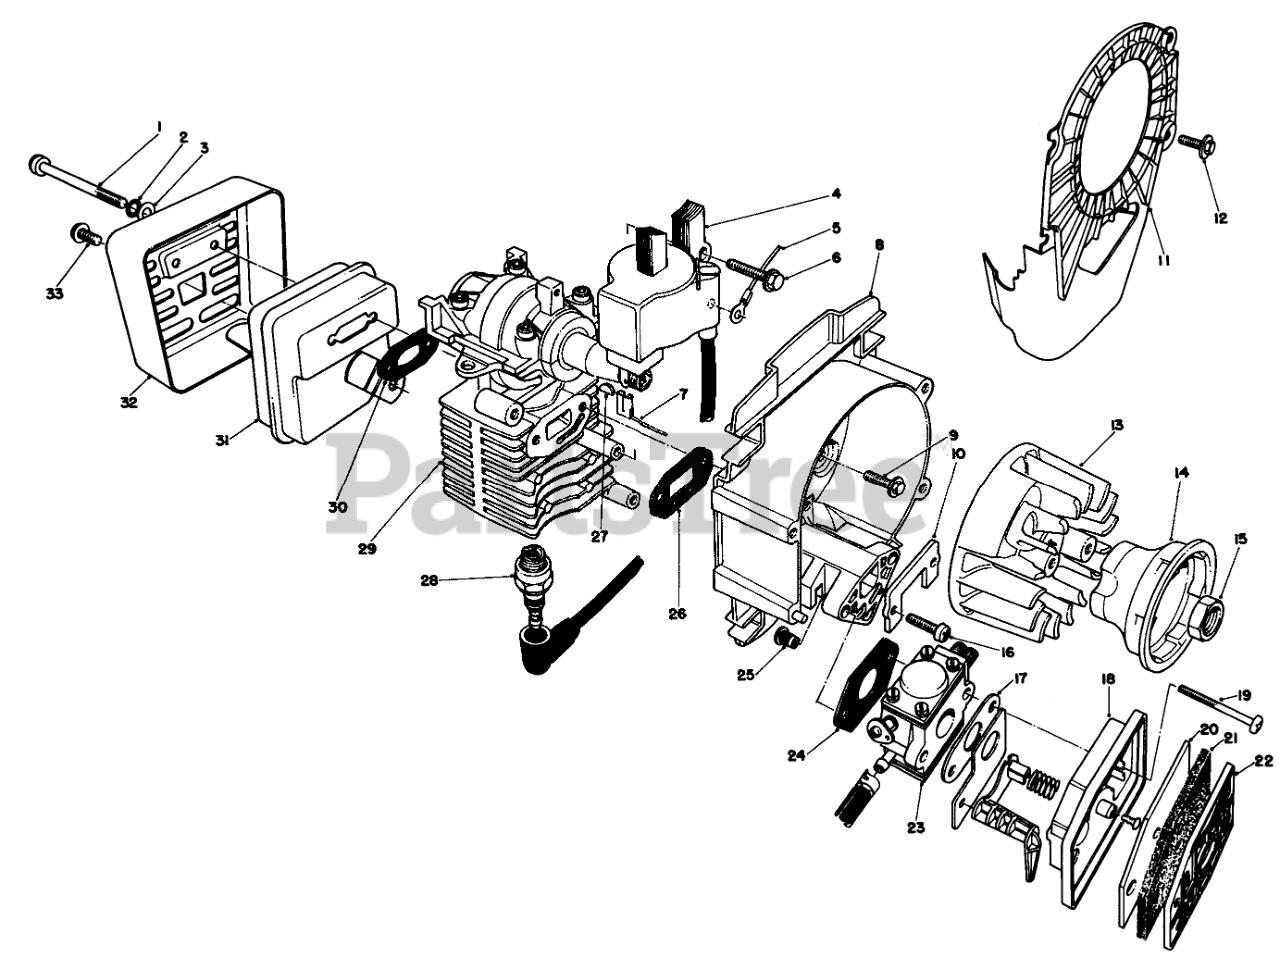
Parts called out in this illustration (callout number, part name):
1	MUFFLER SCREW
2	LOCKWASHER
3	Washer-Plain
4	CDI Module
5	Wire, Ground/Switch
6	Screw CDI
7	Wire, Coil/Switch
8	Backing Plate Assy. (Incl. Ref. #25)
9	Screw, Backing Plate
10	Plate, Stress
11	Cooling Shroud
12	Screw, Shroud
13	Flywheel
14	Cup, Starter
15	NUT-JAM
16	Screw lntake
17	CHOKE GASKET
18	Choke & Spitback Cup Assy.
19	Screw-Carburetor
20	FILTER FELT
21	FILTER FOAM
22	FILTER COVER
23	CARBURETOR ASM
24	CARB. GASKET
25	THREADED INSERT
26	INTAKE GASKET
27	Key Flywheel
28	SPARK PLUG (NGK)
29	SHORT BLOCK ASM
30	EXHAUST GASKET
31	Muffler Assembly
32	MUFFLER SHIELD WA
33	Screw, Muffler Tab
